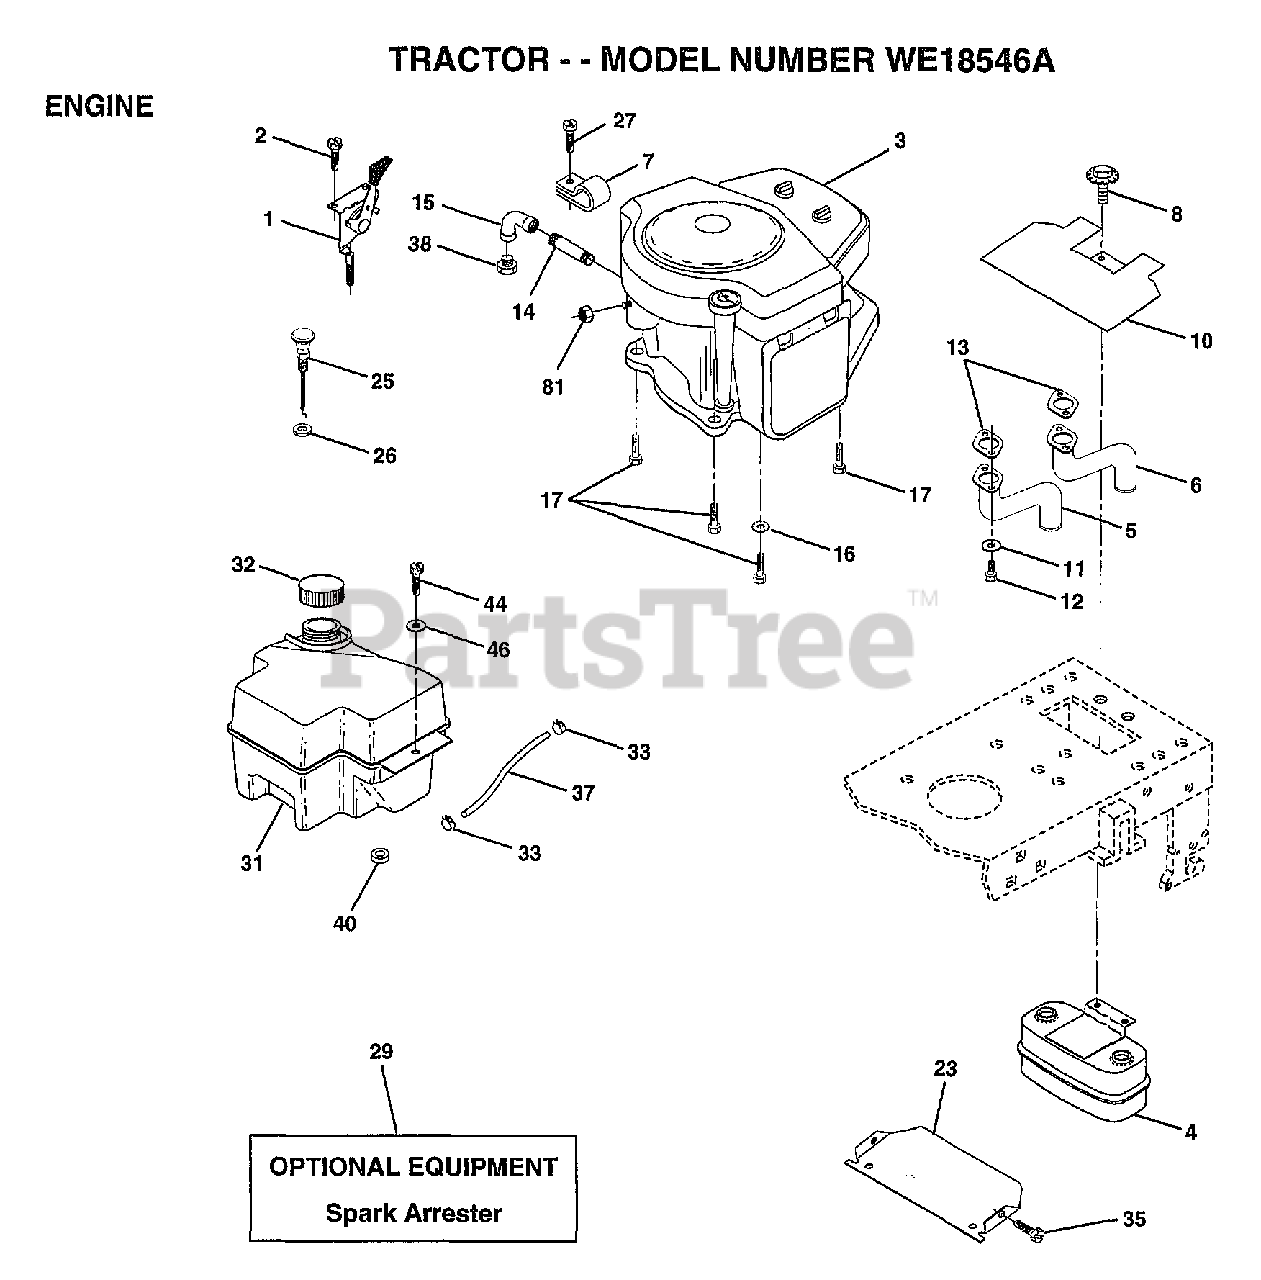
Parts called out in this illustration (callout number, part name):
1	CONTROL THRT 35.5
2	SCREW LT
4	MUFFLER.TW.LOTONE
5	EXHAUST.B&S.18.LH
6	EXHAUST.B&S.18.RH
7	CLAMP.TUBE.DBL.EN
8	BOLT.5/16-18.UNC
10	SHIELD.HEAT.
11	LOCKWASHER
13	GASKET MUFFLER
14	PIPE NIPPLE LT
15	ELBOW
16	LOCKWASHER
17	SCREW LT
23	SHIELD.BRN/DBR.GD
25	CONTROL.CHOKE.37
26	"NUT,KEPS 3/8-24IM"
27	"SCREW-TT,10-32 FL"
31	TANK.FUEL.FRONT.
32	CAP ASM FUEL
33	HOSE CLAMP
35	SCREW
37	LINE FUEL
44	SCREW HEX CRT
46	WASHER
81	NUT
